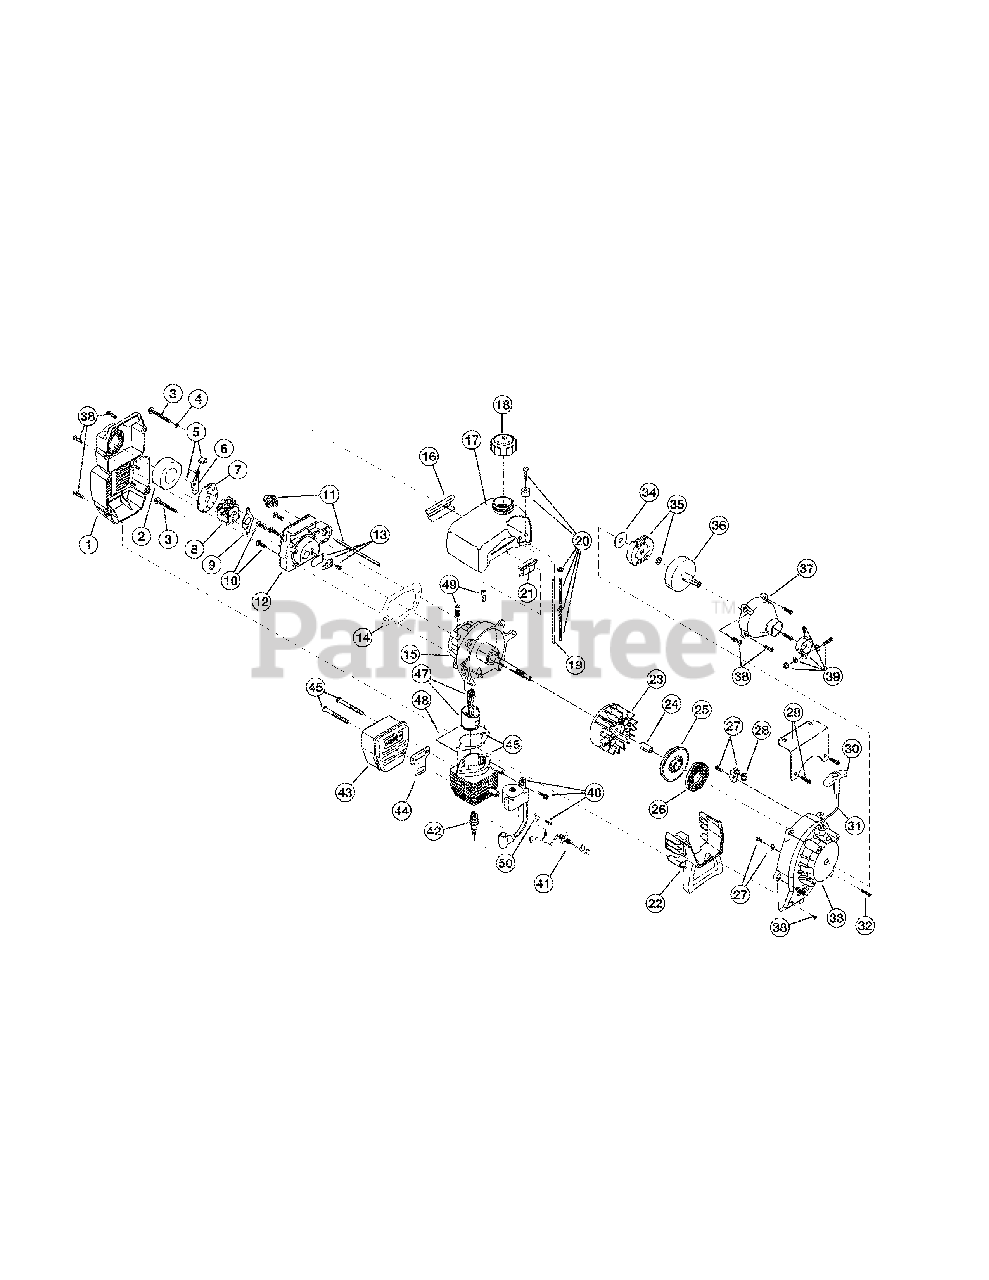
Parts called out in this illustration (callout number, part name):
1	Air Cleaner Assembly (includes 2 & 38)
2	Air Cleaner Filter
3	Carburetor Mounting Screw Assembly
4	Wavey Washer
5	Choke Knob & Screw
6	Choke Lever Assembly (includes 5)
7	Choke Lever & Plate (includes 6)
8	Carburetor Assembly (includes 9 & 20)
9	Carburetor Gasket
10	Carb Mount Screw
11	Primer and Hose Assembly
12	Carb Mount Assembly (includes 10, 13 & 14)
13	Reed Assembly
14	Carburetor Mount Gasket
15	Crank Case Service Assembly (includes 10)
16	Rear Mounting Pad
17	Fuel Tank Assembly (includes 18-20)
18	Fuel Cap Assembly
19	Fuel Return Line
20	Fuel Line Assembly
21	Front Mounting Pad
22	Shroud Extension and Stand (includes 38)
23	Flywheel Assembly
25	Recoil Pulley
26	Recoil Spring
27	Pulley Retainer Assembly
28	Rope Guide
29	Fuel Tank Guard Assembly
30	Pull Handle
32	Housing Screw
33	Starter Housing Assembly (includes items 25-28, 30-32 & 38)
34	Clutch Washer
35	Clutch Rotor Assembly
36	Clutch Drum Assembly
37	Clutch Cover Assembly (includes 38)
38	Clutch Cover Screw
39	Upper Clamp Assembly
40	Module Assembly (includes 50)
41	Wire Lead
42	Spark Plug
43	Muffler Assembly (includes item 44 & 45)
44	Exhaust Gasket
45	Muffler Mounting Bolt Assembly
46	Cylinder Assembly (includes items 48 & 49)
47	Piston & Rod Assembly
48	Cylinder Gasket
49	Cylinder Bolt
50	Ground Tab
